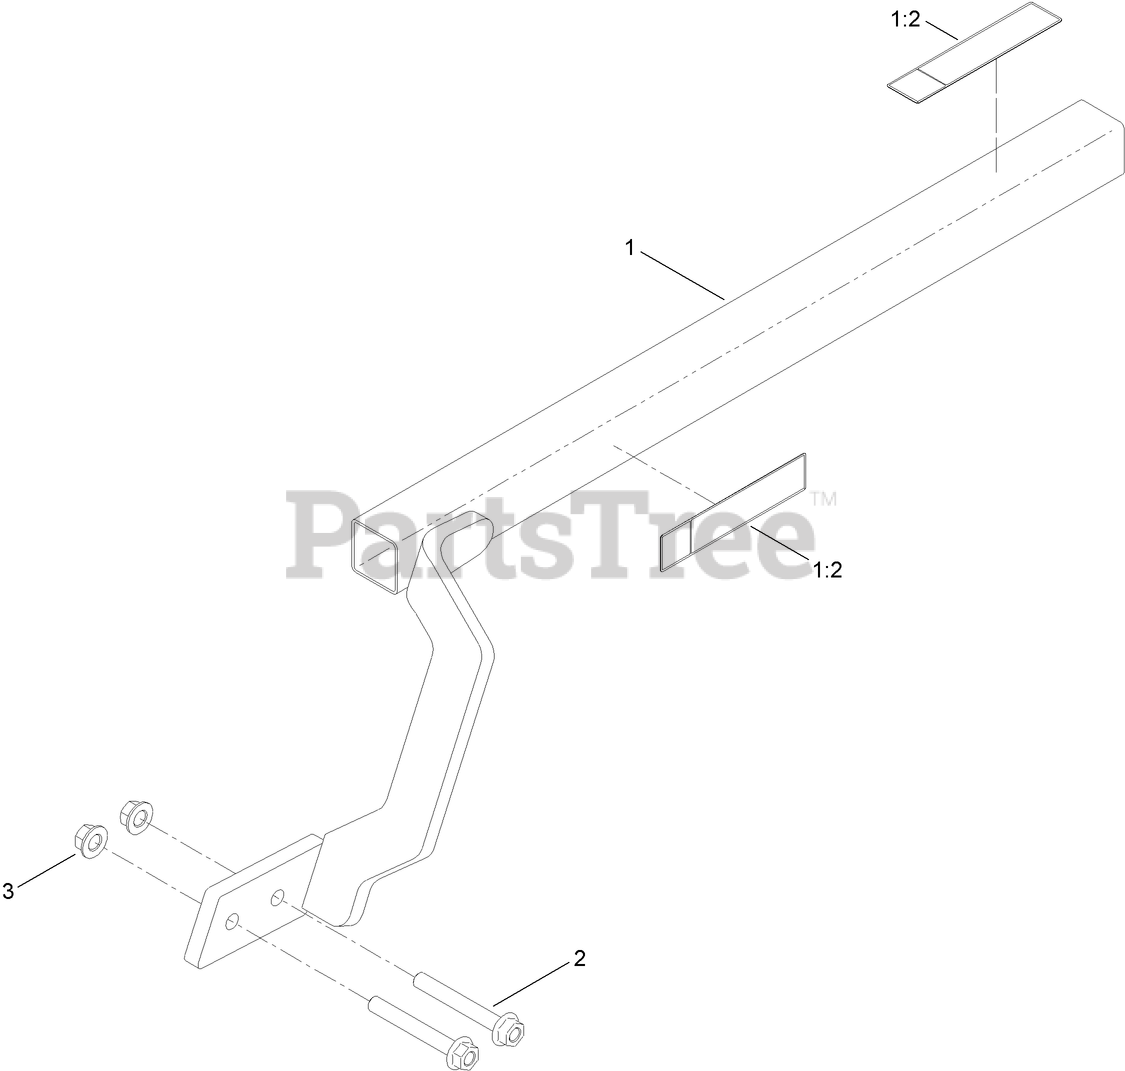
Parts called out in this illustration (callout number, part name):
1	36 INCH RESTRAINT BAR ASM
1:2	DECAL-DANGER, ENTANGLEMENT
3	NUT-HHF
